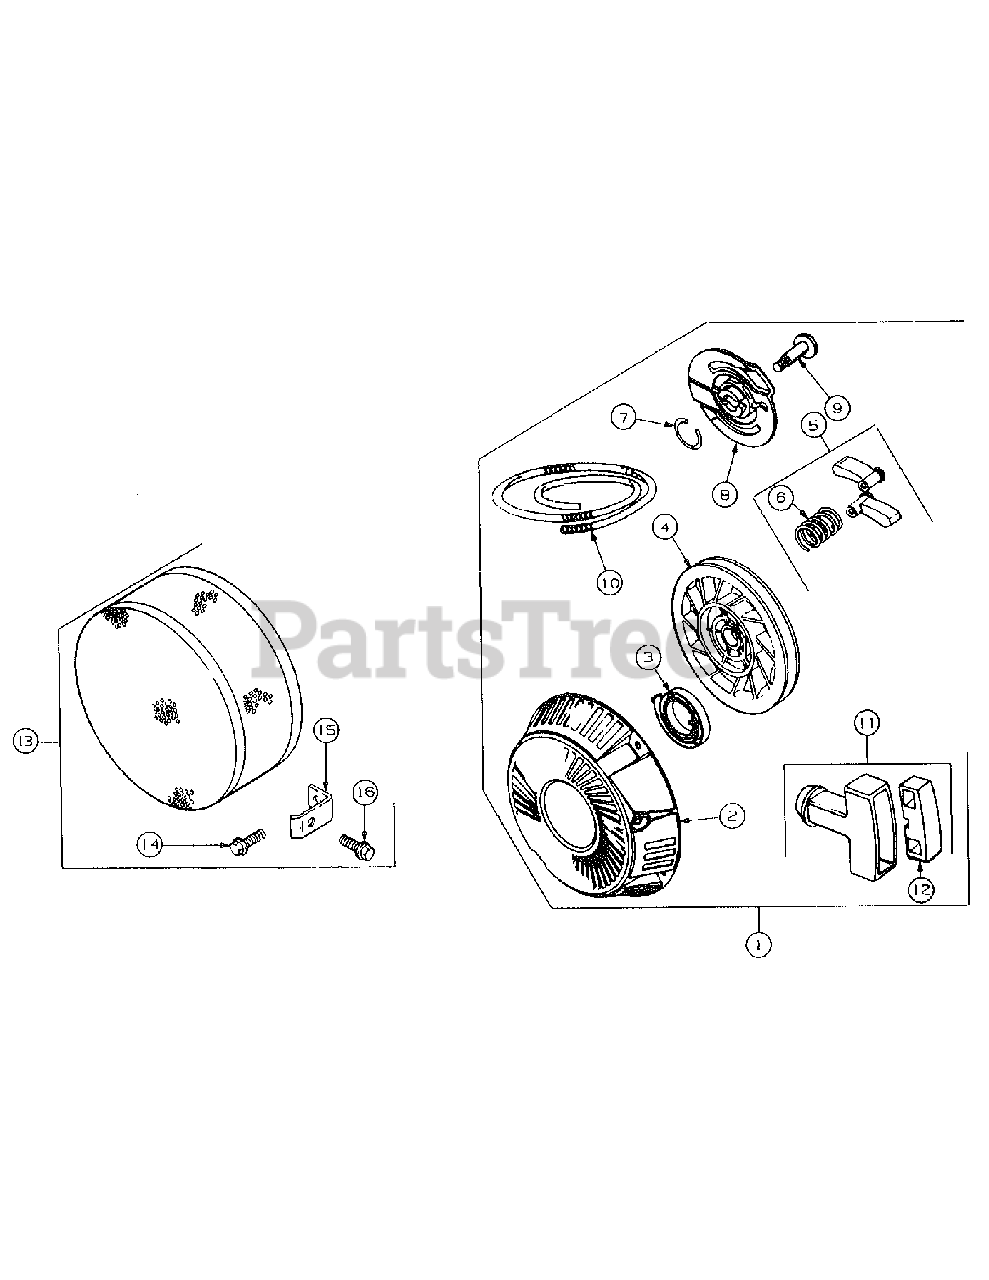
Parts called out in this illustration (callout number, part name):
1	Starter Assembly, Rewind w/Starter hub
2	Housing, Starter
3	Spring, Rewind Starter
4	Pulley, Rewind Starter
5	Dog, Starter
6	Spring, Dog
7	Ring, Retaining
8	Retainer
9	Screw, Retainer
10	Rope, Starter
11	Handle, Rewind Starter
12	Insert, Starter Handle
13	Screen Assembly, Debris
14	Screw, Hex Hd
15	Bracket, Debris Guard
16	Screwm Sem
